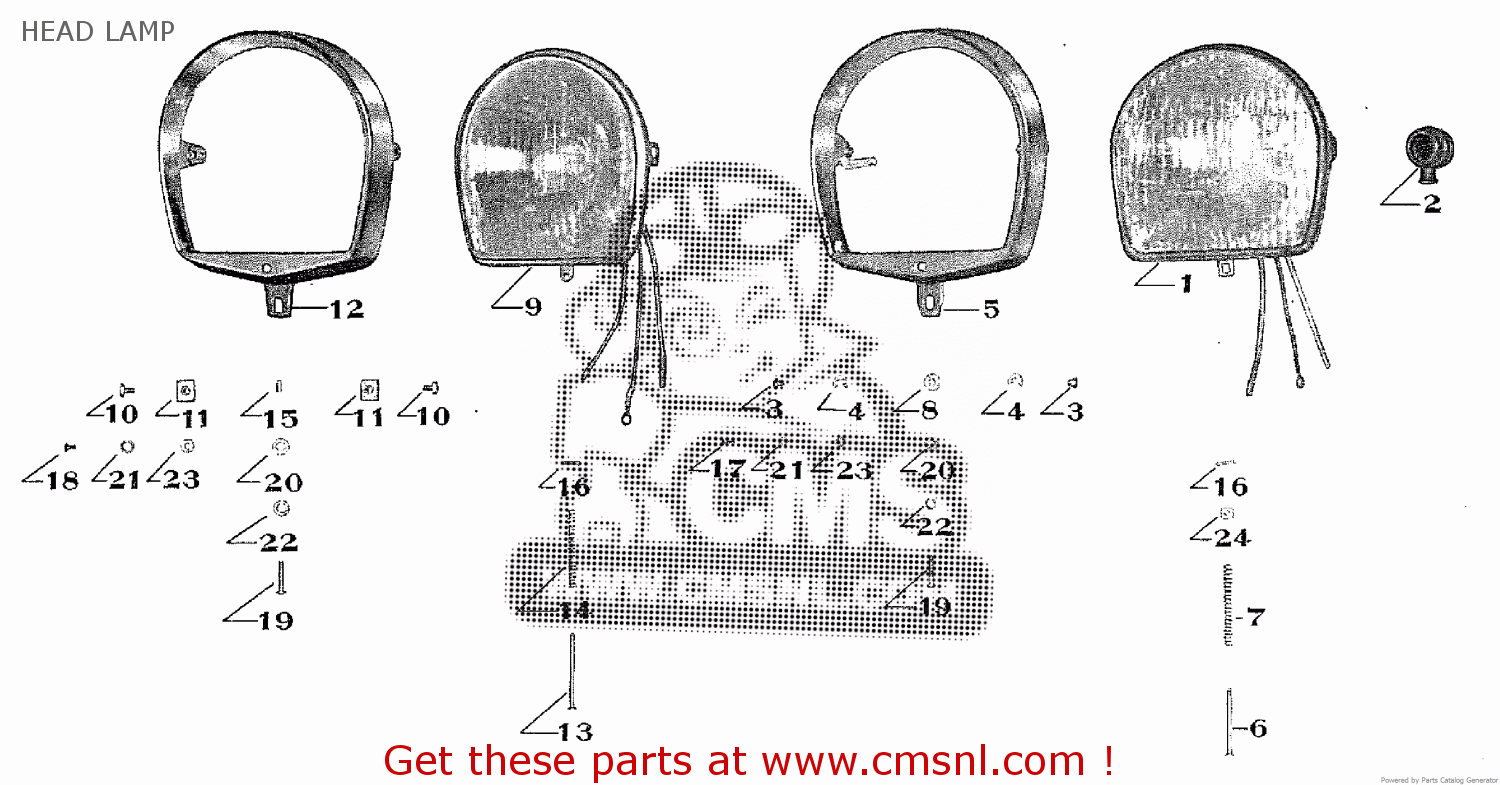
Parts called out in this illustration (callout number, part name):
1	SEAL BEAM COMP.
2	CORD COVER
3	REFLECTOR SET PIN
4	REFLECTOR SET RING
5	FRONT FRAME COMP.
6	7
7	REFLECTOR ADJUSTER SPRING
8	HEAD LAMP SET COLLAR
9	SEAL BEAM COMP.
10	REFLECTOR SET PIN
11	REFLECTOR SET RING
12	FRONT FRAME COMP.
13	14
14	REFLECTOR ADJUSTER SPRING
15	HEAD LAMP SET COLLAR
16	1.6X8 COTTER PIN
17	4X6 SCREW
18	4X6 CROSS SCREW
19	5X20 CROSS SCREW
20	5MM PLANE WASHER
21	4MM PLANE WASHER
22	5MM SPRING WASHER
23	4MM HEXAGON NUT
24	5MM SQUARE NUT
